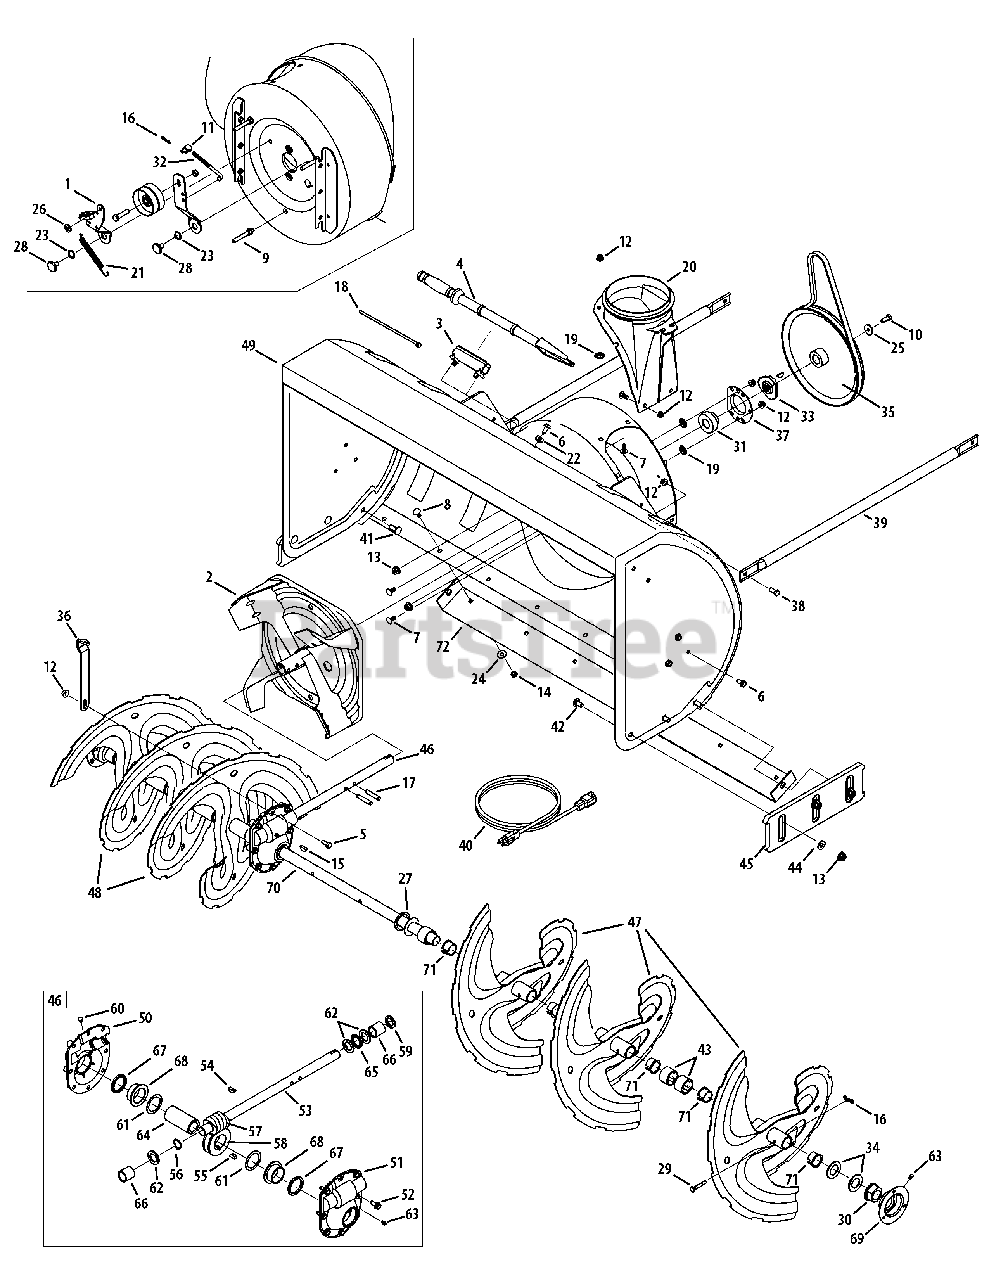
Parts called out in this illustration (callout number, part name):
1	Bracket Assembly, Auger Brake
2	Impeller , 16"
3	Clip, Mounting
4	Tool, Clean-out
5	Screw, Hex Cap, 5/16-18 x 1.0 Gr5
6	Screw, 5/16-18 x .750
7	Screw, Carriage, 5/16-18 x .75
8	Screw, Carriage, 5/16-18 x .75 Stainless
9	Screw w/Stud, 5/16-18 x .4300
10	Screw, Hex Cap Lock, 5/16-24 x .875
12	Nut, Hex Flange Lock, 5/16-18
13	Nut, Hex Flange Lock, 3/8-16
14	Nut, Hex, 5/16-18 Stainless
15	Key, Woodruff, 1/4 x 3/4
16	Pin, Bow-tie Cotter
17	Pin, Spiral, 5/16 x 1.75
18	Cable Tie
19	Nut, Push
20	Adapter, Chute, 6"
21	Spring, Extension
22	Washer, Flat, .349 x .879 .063
23	Washer, Wave, .625 x .885 x .015
24	Washer, Bell., .34 x .872 x .06 Stainless
25	Washer, Flat, .34 x 1.5 x .15 Ht.
26	Washer, .344 x .75 x .12
27	Washer, 1.01 x 1.86 x .06
28	Screw, Shoulder, .625 x .17
29	Pin, Shear, .25 x 1.75
30	Bearing, Flange w/Flats
31	Bearing, Self Aligning
32	Rod, Auger Idler
33	Adapter, Pulley w/Pins
34	Spacer, 1.004 x 1.375 x .25
35	Pulley, Auger Drive, 10.0
36	Bracket, Gear Box Support
37	Housing, Bearing
38	Screw, 5/16-18 x .75 GR5
39	Tube, Support
40	Extension Cord, 110V
41	Screw, Carr,3/8-16 x 1.25
42	Screw, Carriage, 3/8-16 x 1.00
43	Spacer, 1.50 x 1.00 x 1.00
44	Washer, Flat, .385 x .87 x .092
45	Deluxe Skid Shoe
46	Gear Box Assembly
47	Spiral Assembly, LH
48	Spiral Assembly, RH
49	Housing, Auger - 45"
50	Housing Assembly, Auger, RH
51	Housing Assembly, Auger, LH
52	Screw, LD, 5/16-18 x .750
53	Auger Drive Shaft
54	Key, Hi Pro, 3/16 x 3/4
55	Key, 1/4 x 3/4 Dia.
56	External Retainer Ring
57	Gear, Worm
58	Gear, Worm, LH
59	Seal, Oil
61	Wash, Flat, 1.52ID x 2.0 OD
62	Wash, Flat, .88 ID x .38 OD
63	Grease Fitting, 3/16
64	Worm Gear Shaft
65	Bearing, Thrust
68	Flange Bearing
69	Housing, Bearing
70	Axle, Spiral
71	Flange Bushing
72	Shave Plate
